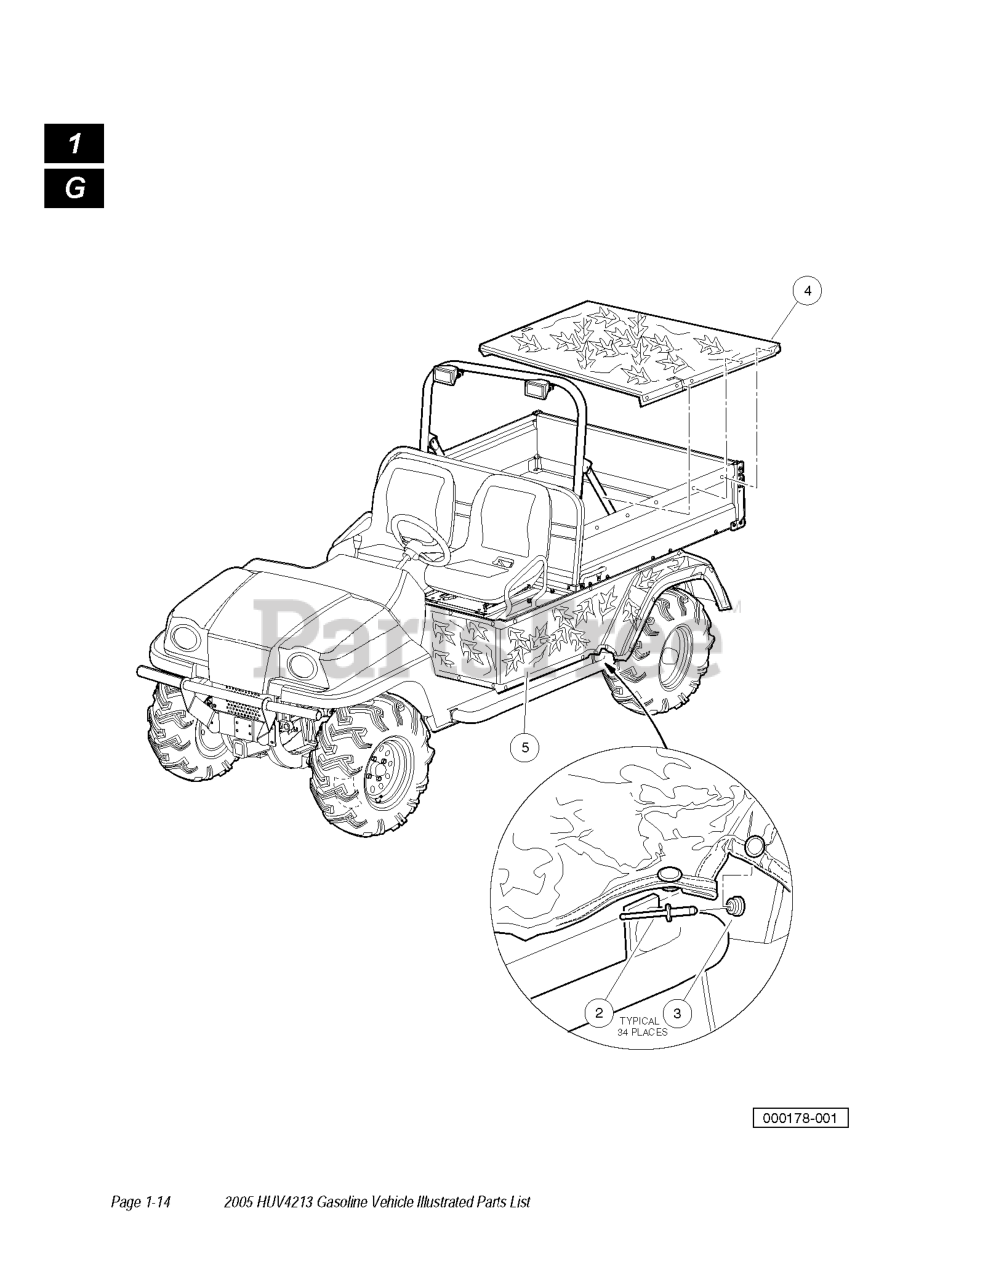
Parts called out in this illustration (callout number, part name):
1	1 2 3 4 Kit, Camo Cover
4	Cover, Camouflage Cargo Box
5	Wrap, Camouflage Rear Body
